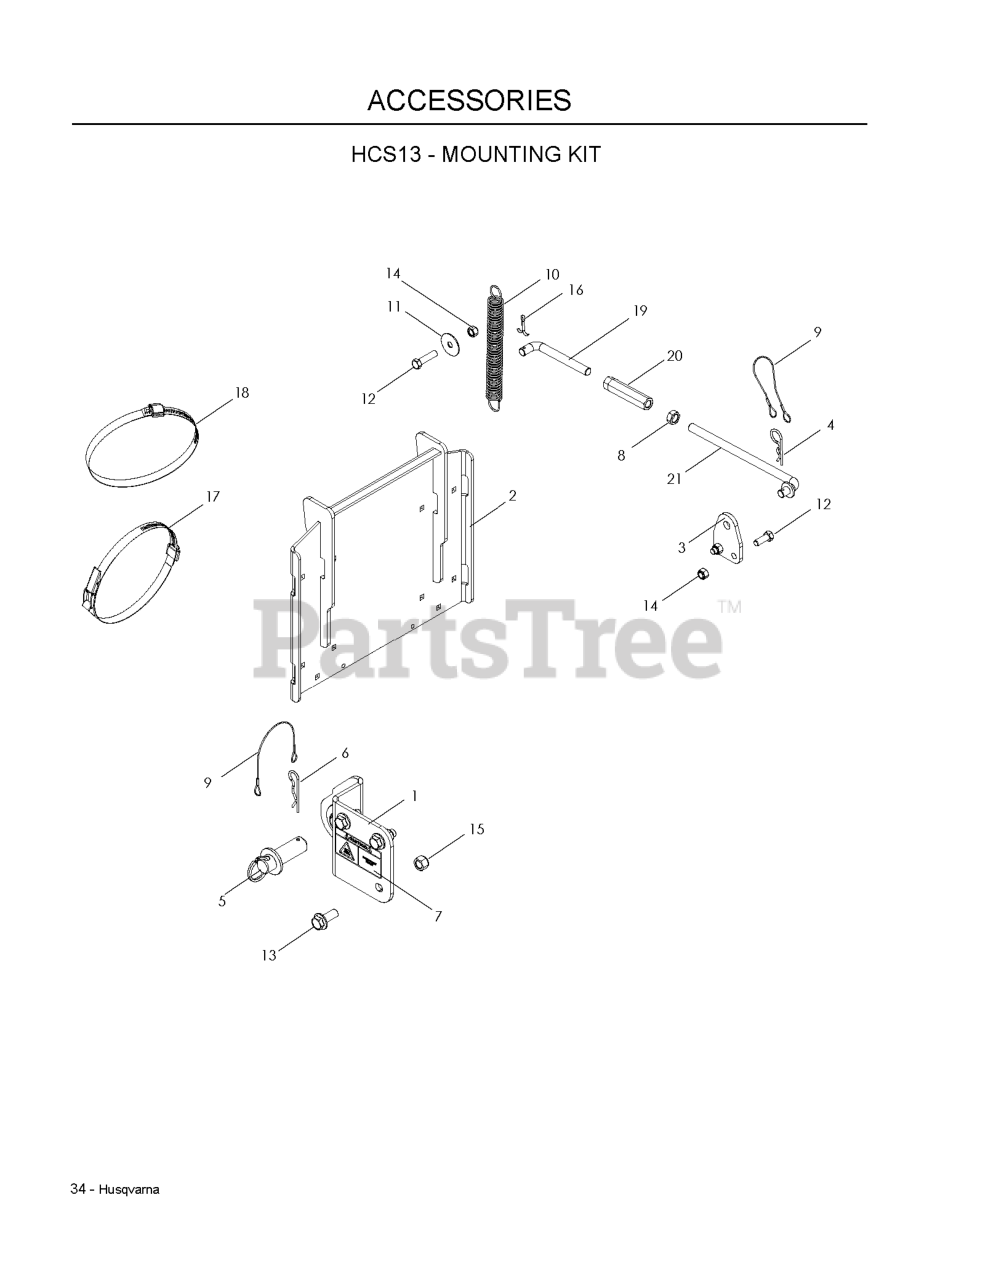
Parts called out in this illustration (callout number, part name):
1	HITCH BRACKET
1	HITCH BRACKET WLDMT
2	REAR GUARD WELDMENT
3	SUPPORT BRACKET
4	HAIRPIN #4
7	DECAL, HOT SURFACE
8	NUT 1/2-20 HEX JAM ZD
11	WASHER, FRICTION
12	HCS 3/8-16X1.GRD.5.ZD
13	HCS 1/2C X 1 1/4 SERRATED HEAD
14	NUT 3/8-16 NYLOC
15	NUT 1/2-13 HEX NYLOC ZD
16	COTTER PIN
17	OVER CTR BAND
18	HOSE CLAMP 4-1/8 TO 7"
19	SUPPORT LINKAGE, LH
20	TURNBUCKLE, 1/2
21	SUPPORT LINKAGE, LRG
